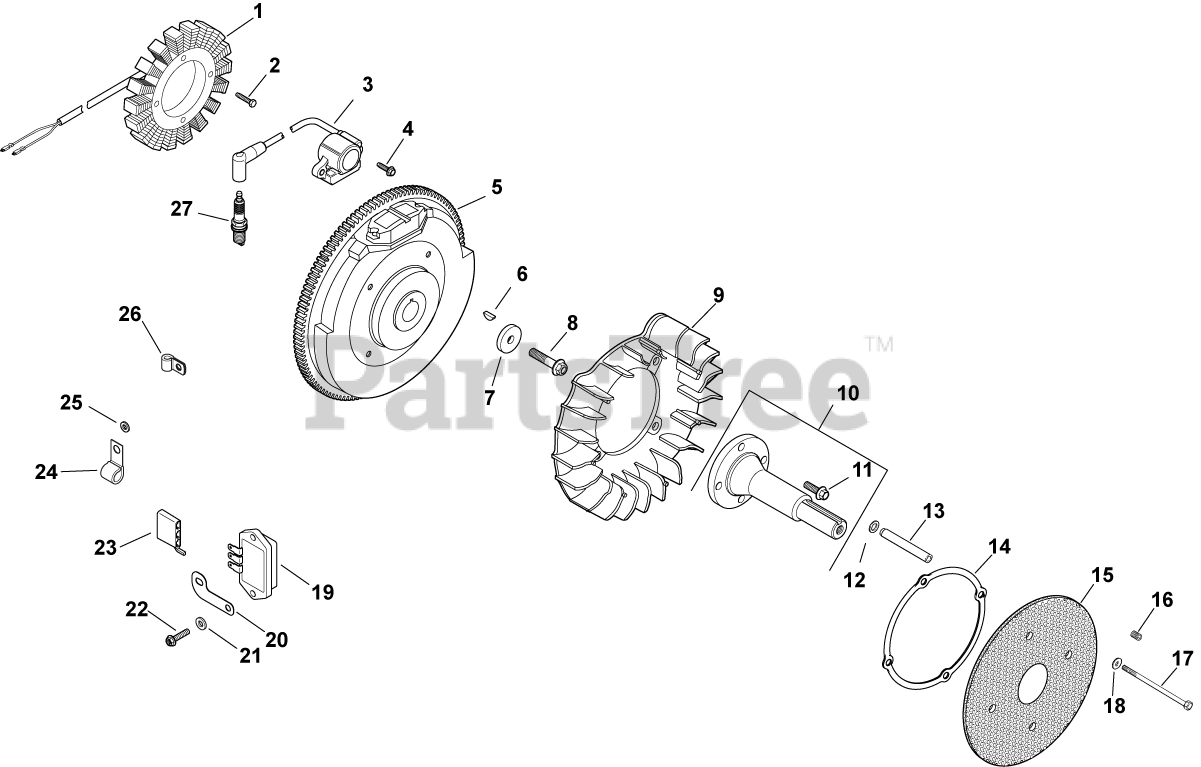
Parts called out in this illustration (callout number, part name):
1	KIT, 15 / 20 AMP STATOR
2	SCREW, M5X0.8X25 - (#25086402S)
3	KIT, MODULE IGNTN (CDI FIXED)
4	SCREW, FLG THD FRM M5X.8X20-(#25086399S)
6	KEY, 3/16" X 5/8"
7	WASHER, FLAT 13/32"
8	SCREW, FLG M10X1.5X45 - (#25086361S)
9	FAN USE 24 755 253-S
10	KIT, FRONT DRIVE SHAFT
11	SCREW, FLG M8X1.25X25
12	WASHER, SPRING 10 MM
14	RING, SUPPORT USE 25 141 08-S
15	SCREEN, GRASS
16	SCREW, SKT SET #10-24X1/4"
17	SCREW, CAP M6X1.0X99.5
18	WASHER, FLAT 1/4" (O.D. 5/8")
19	REG/RECT-15 AMP (KM)-USE 41 403 10-S
20	BRACKET, GROUND STRAP USE 24 518 12-S
21	WASHER, FLAT 3/16"
22	SCREW, PHL HD #11-16X7/8"
23	CONNECTOR
24	CLIP, CABLE
25	WASHER, FLAT 1/4" (O.D. 1/2")
26	CLIP, TUBE & WIRING (KM)
27	PLUG, SPARK (STD)
